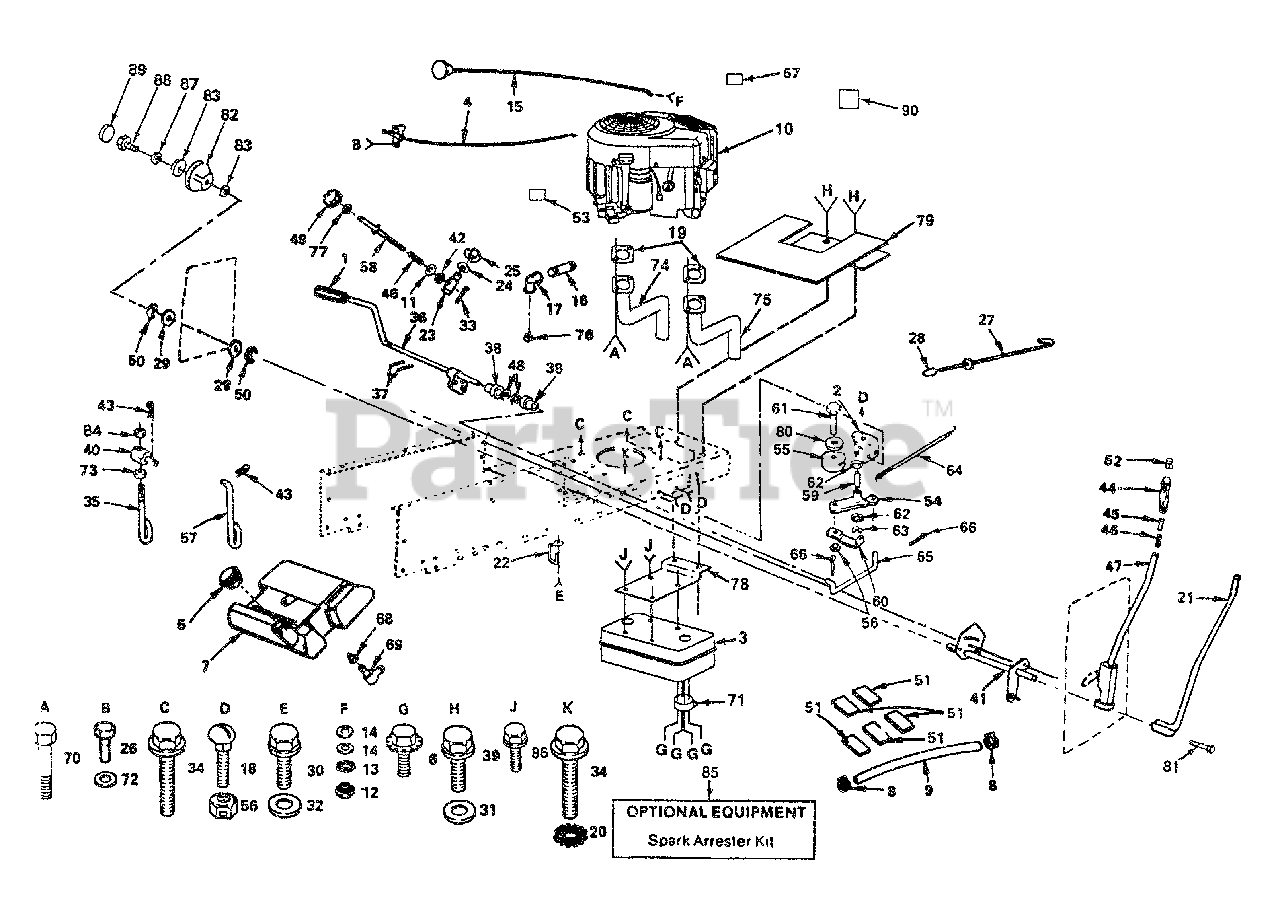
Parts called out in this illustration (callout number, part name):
1	Pedal Cover
2	Bracket Assembly-Clutch
4	Control, Throttle
6	Screw-Spider Lock
8	Hose Clamp
10	Engine Briggs & Stratton 15 H.P., Model Number 303777 Type No. 0015-02
11	Washer 13/32 x 5/8 x 16 Ga.
12	Nut-Hex 3/8-24
13	Washer, Lock, External Tooth 3/8
14	Washer 13/32 x 13/16 x 16 Ga.
15	Control-Choke
16	Std. Pipe Nipple
17	90° Elbow 3/8 NPT
18	Bolt-Carr. 3/8-16 x 3/4
19	Gasket, Muffler
20	Washer, Lock 3/4
21	Rod Assembly-Lever
22	Retainer-Belt, Chassis, L.H.
23	Trunnion-Stop, Depth
24	Washer 15/32 x 3/4 x 16 Ga.
26	Screw-Hex Washer Hd. Thd. Cutting 1/4-20 x 1/2
27	Rod-Brake, Park
28	Plunger Cap
29	Washer 29132 x 1-1/4 x 16 Ga.
30	Screw-Hex Washer Thd. Rolling 3/8-16 x 3/4
31	Washer 13/32 x 1 x 14 Ga.
32	Washer 13/32 x 1-3/16 x 16 Ga.
33	Cotter Pin 3/32 x 1/2
34	Screw-Hex Washer Hd. Thd. Rolling 3/8-16 x 1 1/2 Type TT
35	Lift Link-Adjustable
36	Shaft Pedal Foot
37	Roll Pin 3/16 x 1
38	Bearing, Nylon
39	Screw 5/16-18 x 3/4
40	Trunnion, Lift
41	Shaft Assembly-Lift
42	Nut-hex Special
43	Retainer Spring
44	Grip-Handle
45	Plunger-Lever Lift
46	Spring
47	Lever Assembly, Hand Kit
48	Washer 21/32 x 1 x 16 Ga.
49	Handle-Adjust, Lift
51	Pad-Spacer
52	Button, Plunger
53	Decal, Air Cleaner
54	Arm Assembly, Idler
55	Pulley-Idler
56	Locknut 3/8-16
58	Rod-Adjust, Lift
60	Retainer-Belt
61	Bolt-Hex 3/8-16 x 1-1/2
62	Washer-Hardened
64	Spring-Return, Clutch
65	Link-Clutch
66	Pin-Cotter 1/8 x 3/4
67	Decal, Engine instruction
69	Stem-Tank, Fuel
70	Bolt, Metric
71	Deflector, Muffler
72	Washer 9/32 x 5/8 x 16 Ga.
73	Nut Hex Jam 7/16-20
74	Tube Assembly- Exhaust-L.H.
75	Tube Assembly-Exhaust- R. H.
77	Nut-Hex Jam 3/8-16
78	Muffler, Bracket-Mounting
79	Heat Shield
80	Washer 13/32 x 13/16 x 16 Ga.
81	Bolt, Hex 3/8-16 x 1-1/2
82	Scale, Height Indicator
83	Washer 11/32 x 1-1/2 x 10 Ga.
84	Nut, Crownlock 7/16-20
85	Spark Arrestor Kit
86	Screw, Hex Washer Hd, Thread Cutting 1/4-20 x 1/2
87	Washer, Lock
88	Bolt, Hex 5/16-18 x 1
89	Plug, Hole
90	Decal, Engine Instruction
